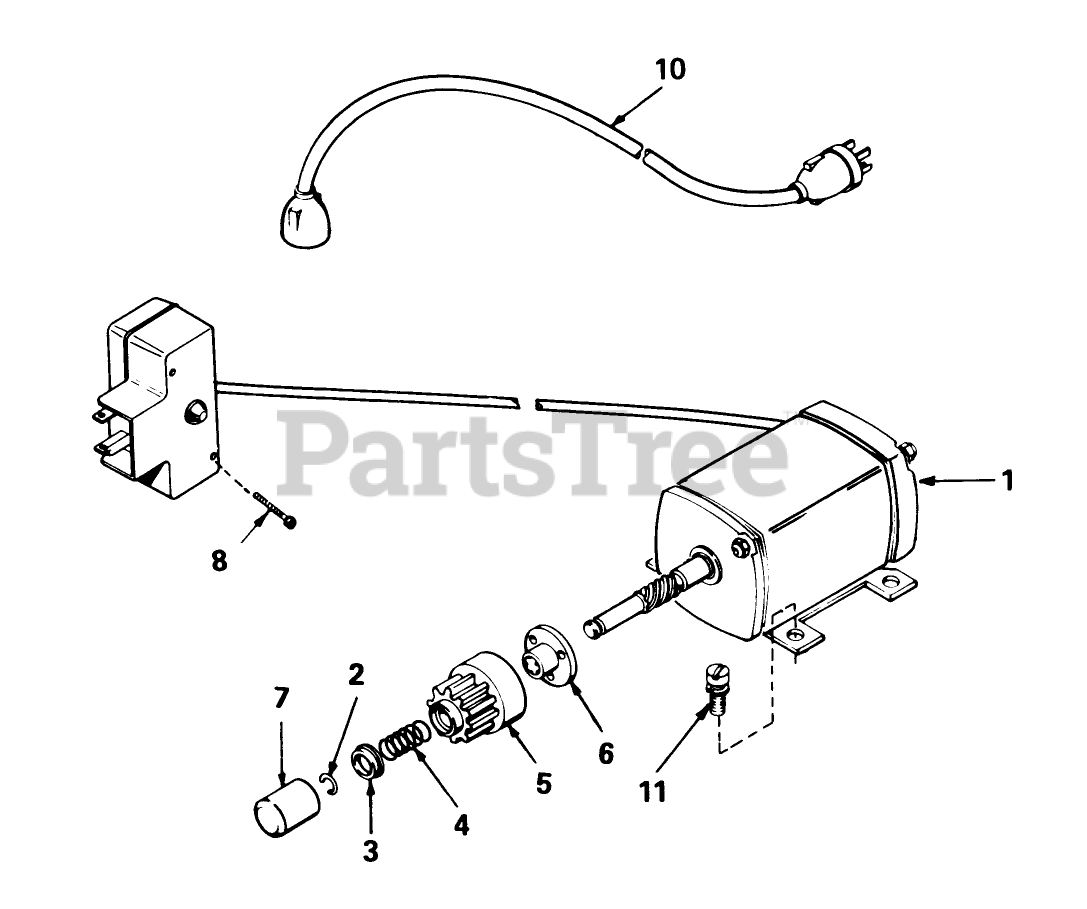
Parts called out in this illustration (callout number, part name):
1	Motor, Cranking (CSA Approved) (Incl. Ref. #2 thru 11)
2	Ring-Retainer
3	Retainer-Spring
4	Spring-Anti Drift
5	Gear
6	Nut-Engaging
7	Cover-Dust
8	Screw
10	Cord-Extension (10-6)
11	Screw
11	Screw (1/4-20x1/2)
